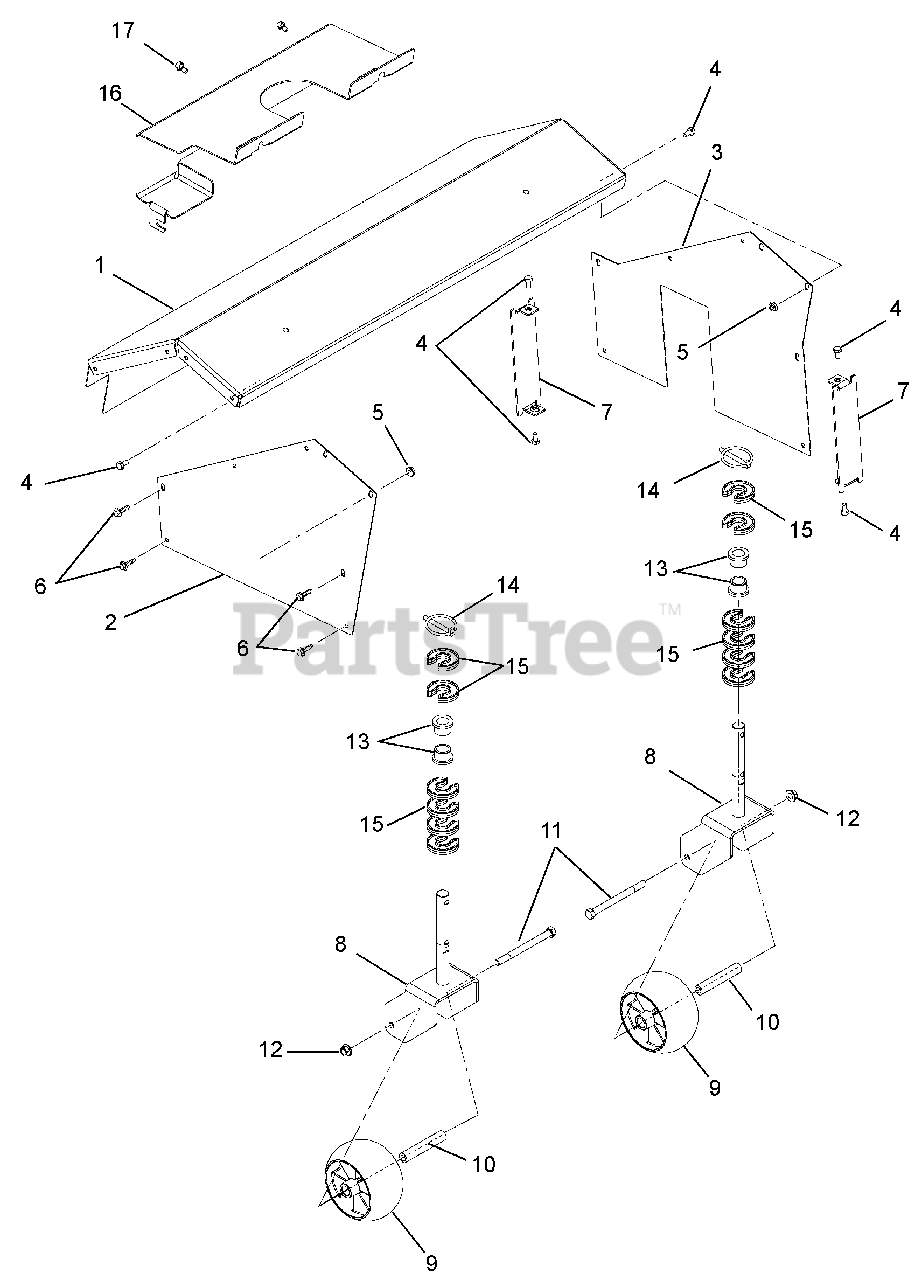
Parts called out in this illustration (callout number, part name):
1	COVER WITH DECALS, 28"BRUSH
1	DECAL, DANGER -POWER BRUSH-CE
1	Decal, Ariens Heritage
1	DECAL, CAUTION - BRUSH
2	COVER,RH SIDE BRUSH
3	COVER,LH SIDE BRUSH
4	@BLT-HEX .25-20X.50 GR5 YWZC
5	@NUT-LK-TOP-FLG .25-20 YWZC
6	SCR-TAP .25-20X.50 HWH TR YWZ
7	COVER,END
8	FORK, CASTER-BRUSH
9	WHEEL, CASTER - 5"OD
10	SPACER, CASTER WHEEL
11	@BLT-HEX .38-16X4.50 GR5 YWZC
12	@NUT-LK-TOP-FLG .38-16 YWZC
13	BUSHING, FLANGE .75X.75X1.0
14	PIN, LYNCH - .25 X 1.25
15	CLIP-HOC FIXED
16	COVER, FRONT SHAFT - CE
17	SCR-TAP .25-20X.50 LGHWH TR YZ
